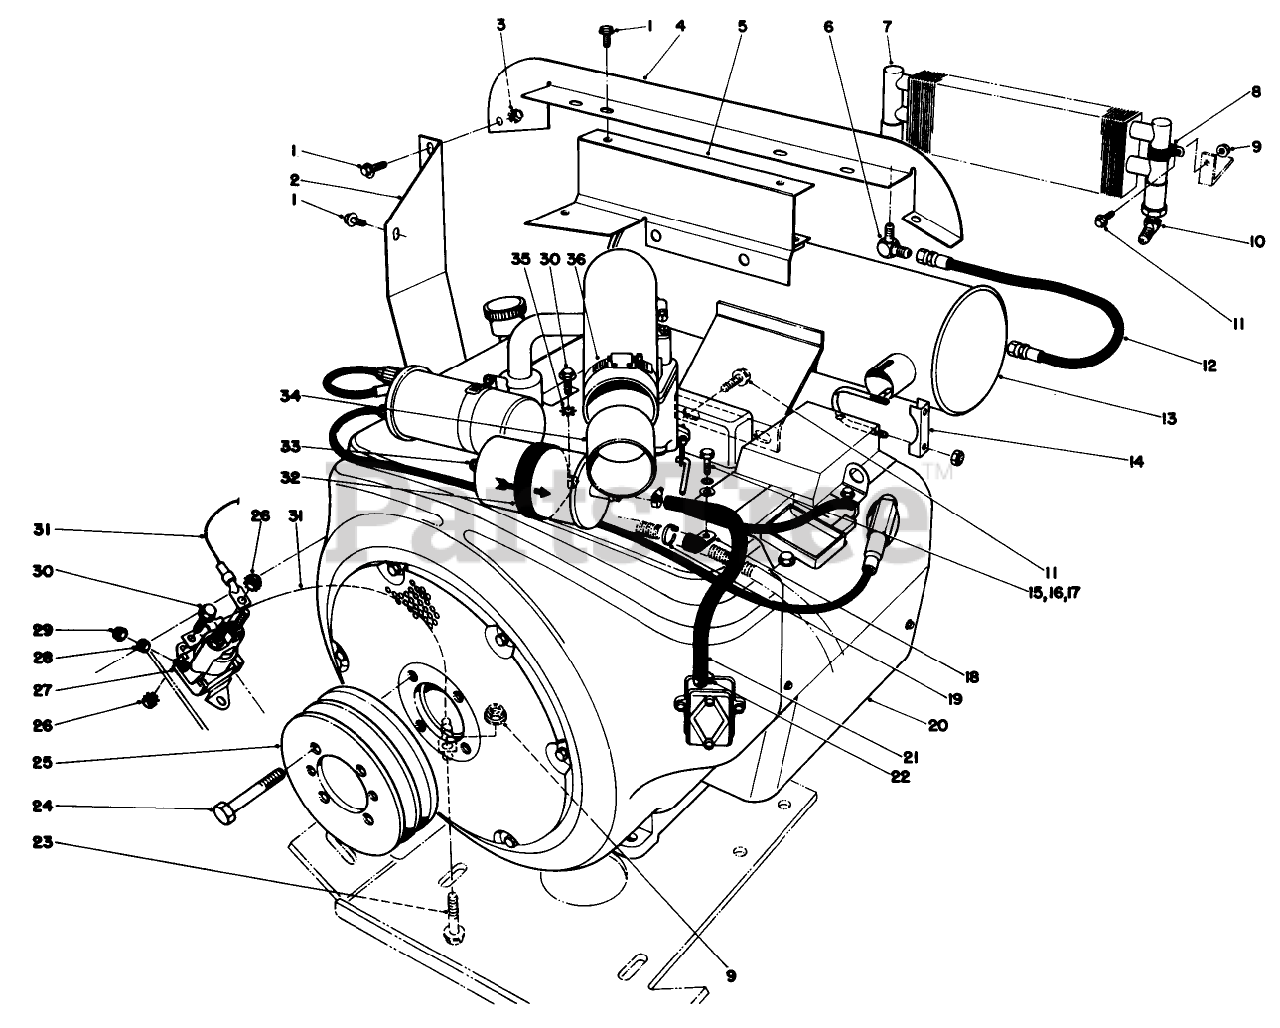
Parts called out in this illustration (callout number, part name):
1	SCREW-HHF
3	NUT-LOCK, NI
8	CLAMP-R
9	NUT-HHF, WHIZ
10	ELBOW
11	SCREW-HHF
12	OIL HOSE ASM
15	SCREW-HH
16	SCREW-HH
17	WASHER-FLAT
18	CLAMP-R
22	CLAMP-HOSE
23	SCREW-HHF
26	NUT-KEPS
28	NUT-HEX
29	NUT-KEPS
30	SCREW-HH
32	56035A/56036A 21 SE
35	WASHER-LOCK
36	CLAMP-HOSE
